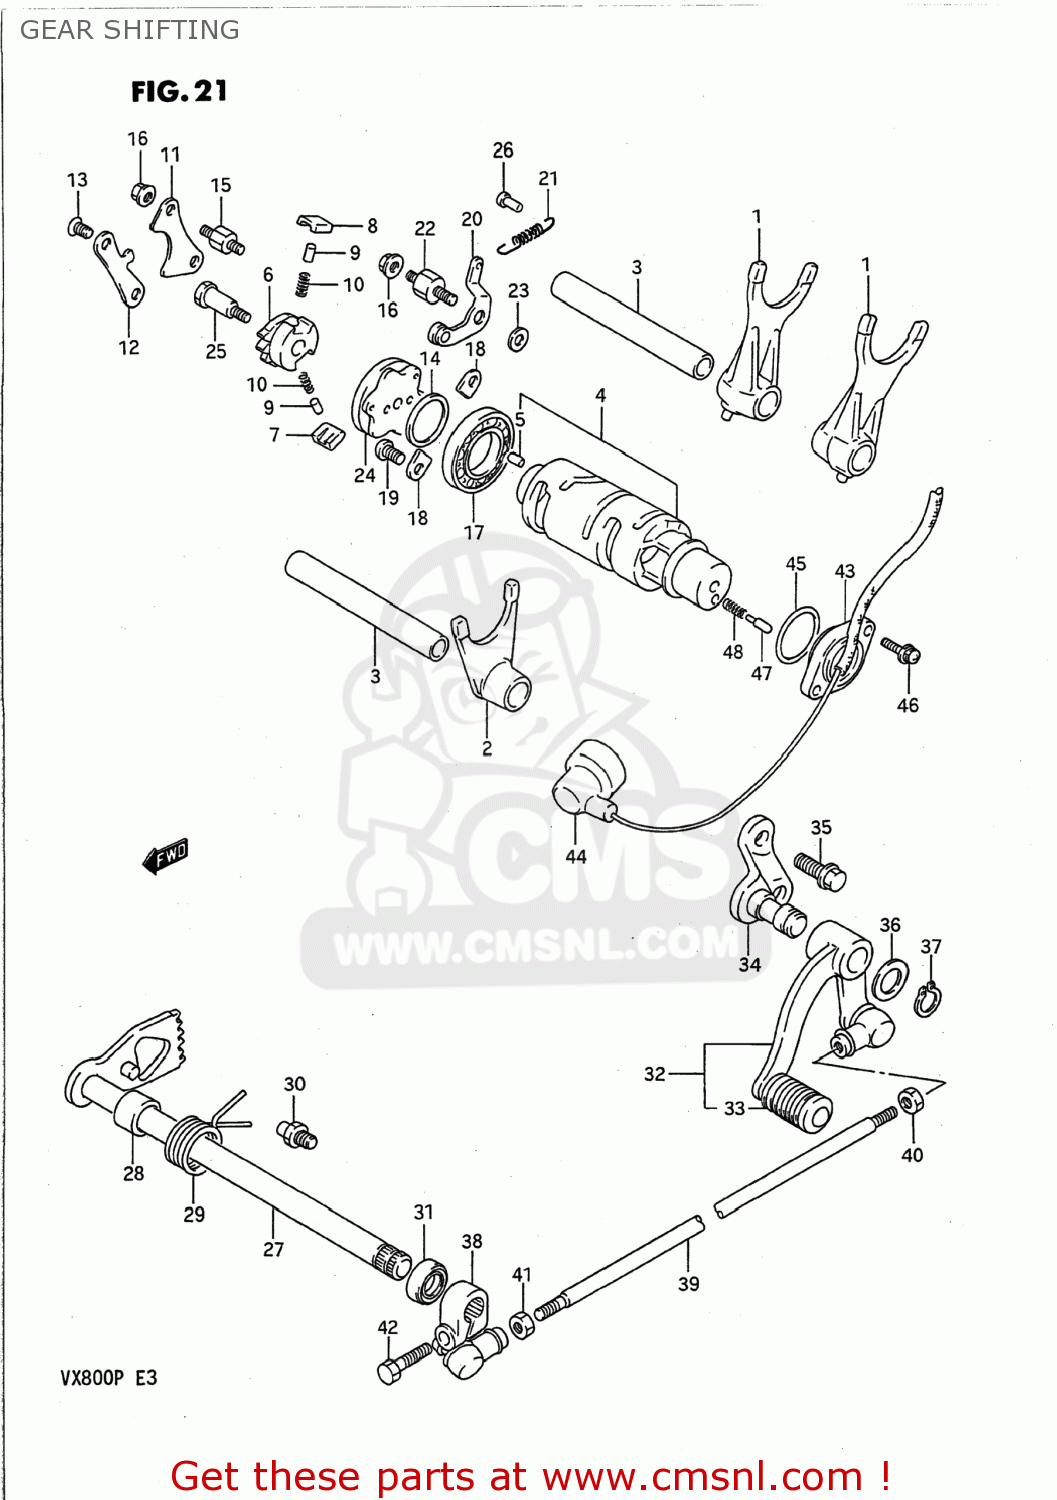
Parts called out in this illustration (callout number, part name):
1	FORK,GEAR SHIFT NO.1
2	FORK,GEAR SHIFT NO.2
3	SHAFT,GEAR SHIFT FORK(L:115)
4	CAM,GEAR SHIFT
5	PIN
6	GEAR,GEARSHIFT CAM DRIVE
7	PAWL,GEAR SHIFT NO.1
8	PAWL,GEAR SHIFT NO.2
9	PIN(5X8)
10	SPRING
11	LIFTER,GEAR SHIFT POLE
12	GUIDE,GEAR SHIFT CAM
13	SCREW
14	WASHER(25X32X3)
15	BOSS,SHIFT PAWL LIFTER
16	NUT
17	BEARING
18	RETAINER,SHIFT CAM,R BEARING
19	SCREW 6X12
20	STOPPER,GEAR SHIFT CAM
21	SPRING,SHIFT CAM STOPPER
22	SUPPORT,CAM STOPPER ARM
23	WASHER
24	PLATE,GEAR SHIFT CAM
25	PIN,SHIFT CAM DRIVEN GEAR
26	RIVET
27	SHAFT,GEAR SHIFT
28	SPACER(12X20X15.3)
29	SPRING
30	STOPPER,GEAR SHIFT CAM
31	OIL SEAL
32	LEVER ASSEMBLY,GEAR SHIFTING
33	RUBBER,GEAR SHIFT PEDAL
34	BRACKET,GEAR SHIFT LEVER
35	BOLT
36	WASHER(12.5X20X1)
37	CIRCLIP,12 MM
38	ARM,GEAR SHIFT LINK
39	ROD,GEAR SHIFT LINK
40	NUT
41	NUT 6MM
42	BOLT
43	BASE ASSY,NEUTRAL SW
44	CAP,OIL PRESSURE SWITCH
45	O RING(D:2.4,ID:26.2)
46	SCREW
47	PIN(5X15.5)
48	SPRING
